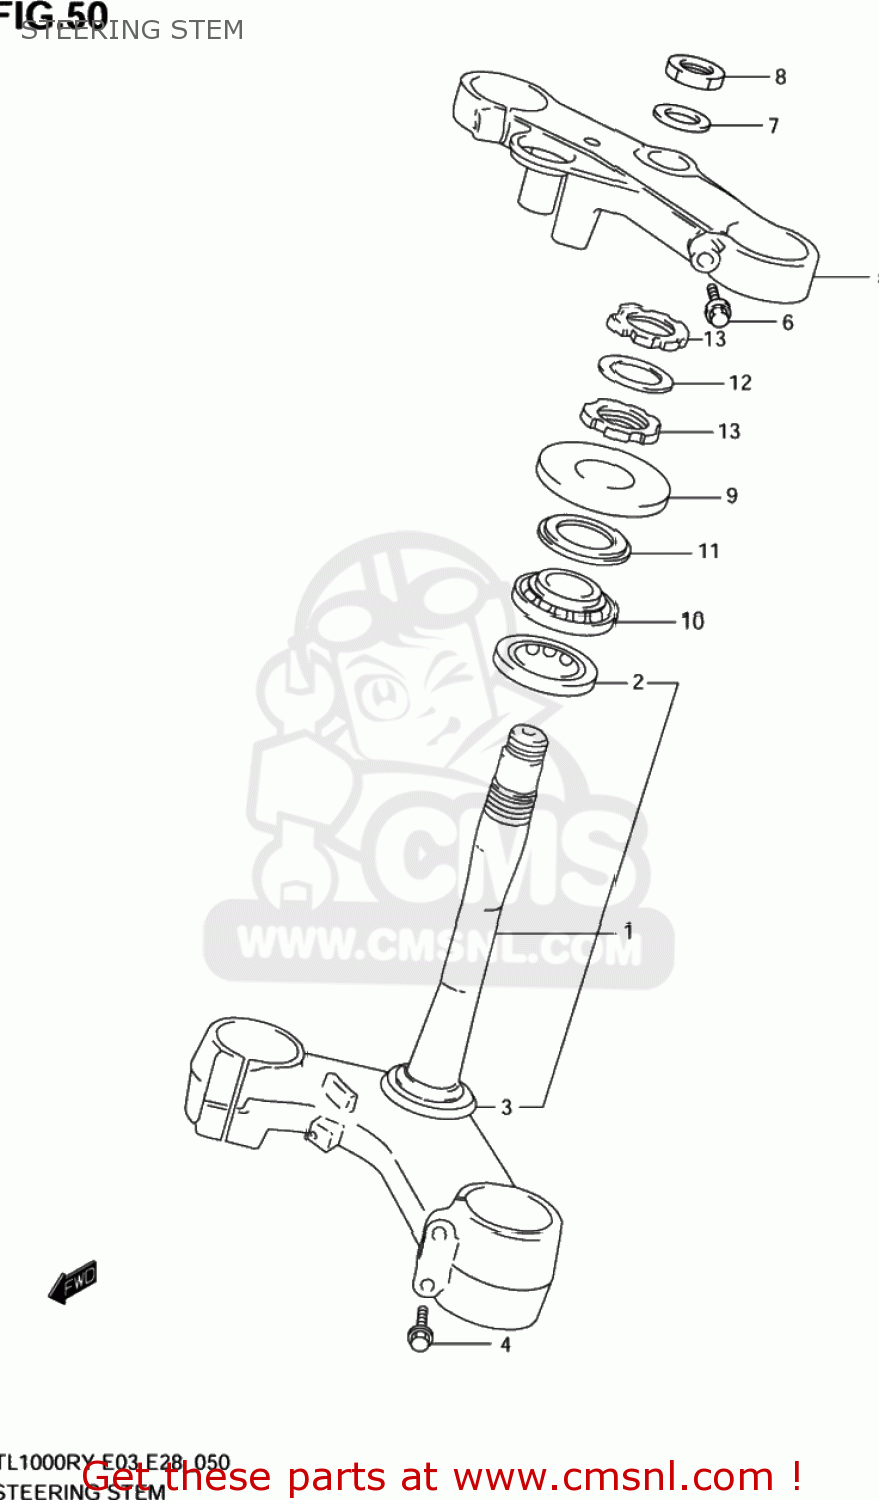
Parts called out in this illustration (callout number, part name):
1	STEM,STEERING
2	BEARING(30X55X17)
3	SEAL,STEERING LWR
4	BOLT
5	HEAD,STEERING STEM
6	BOLT
7	WASHER,STEM HEAD(24.5X34X1.6)
8	NUT
9	SEAL,STEERING LWR
10	BEARING(30X55X17)
11	COVER,STEERING UPR
12	WASHER,STEERING STEM
13	NUT,STEERING STEM
